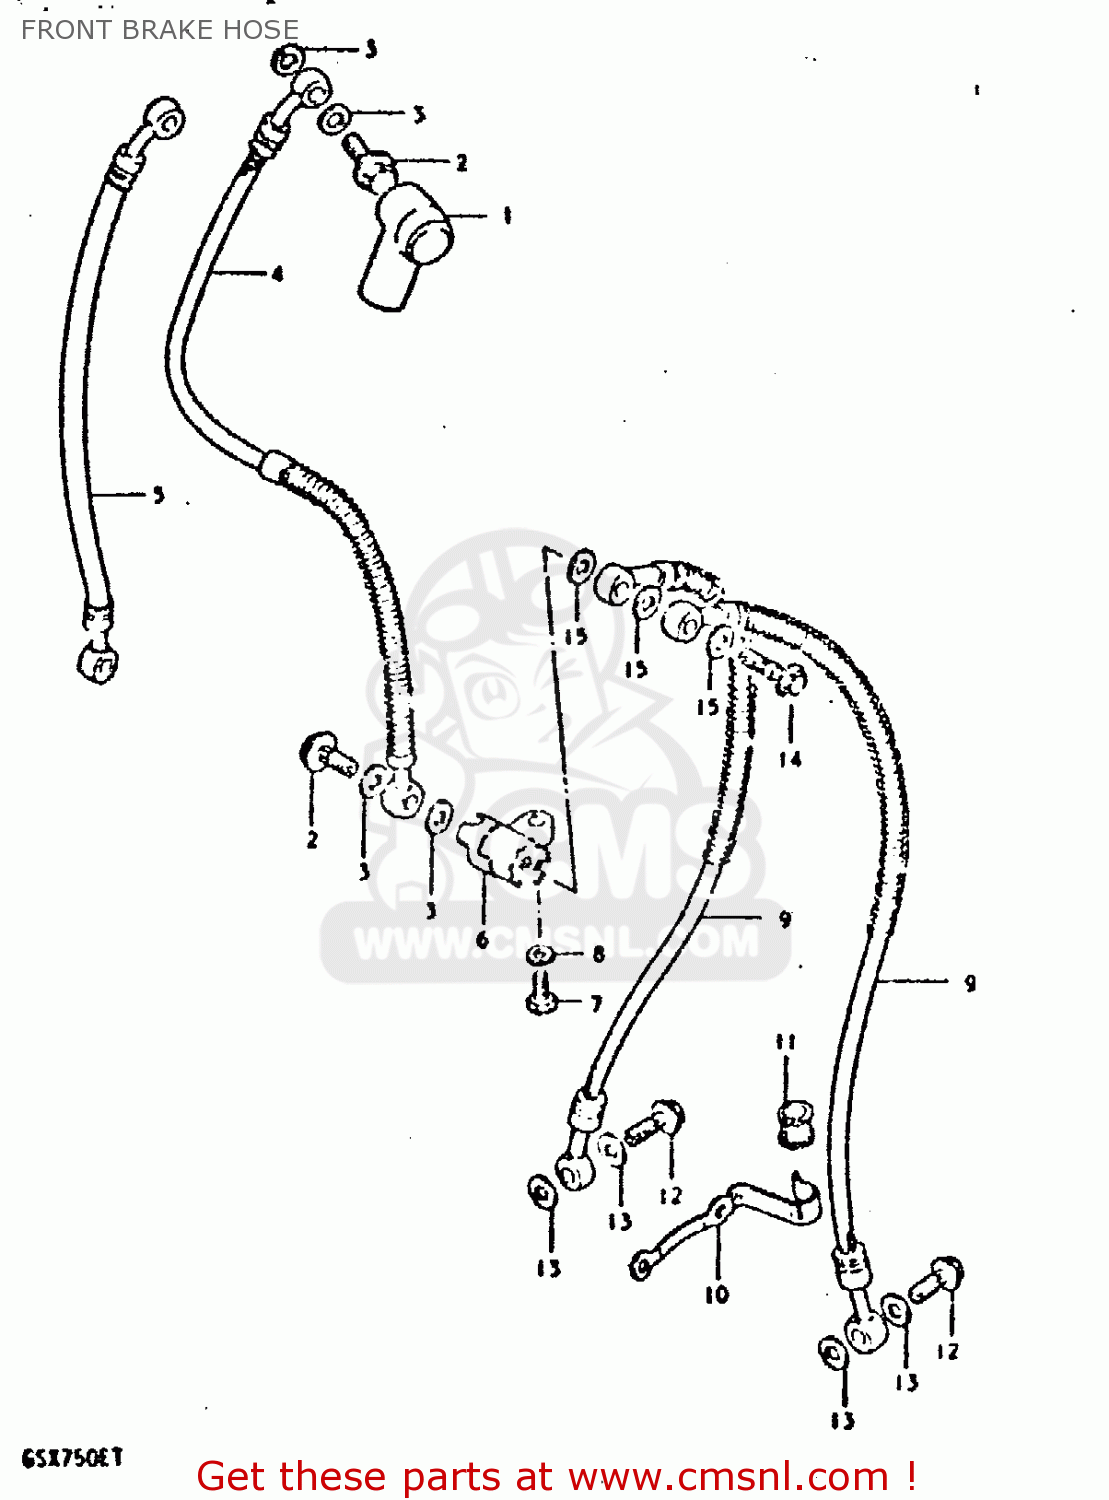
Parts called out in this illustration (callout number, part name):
1	BOOT,MASTER CYLINDER
2	BOLT,UNION
3	WASHER
4	HOSE,FRONT BRAKE
5	HOSE,FRONT BRAKE
6	JOINT,BRAKE HOSE
7	BOLT
8	LOCK WASHER
9	HOSE,BRAKE NO.2
10	GUIDE,BRAKE HOSE NO.2
11	BUSH,BRAKE HOSE GUIDE,NO.2
12	BOLT,UNION
13	WASHER
14	BOLT,UNION
15	WASHER
